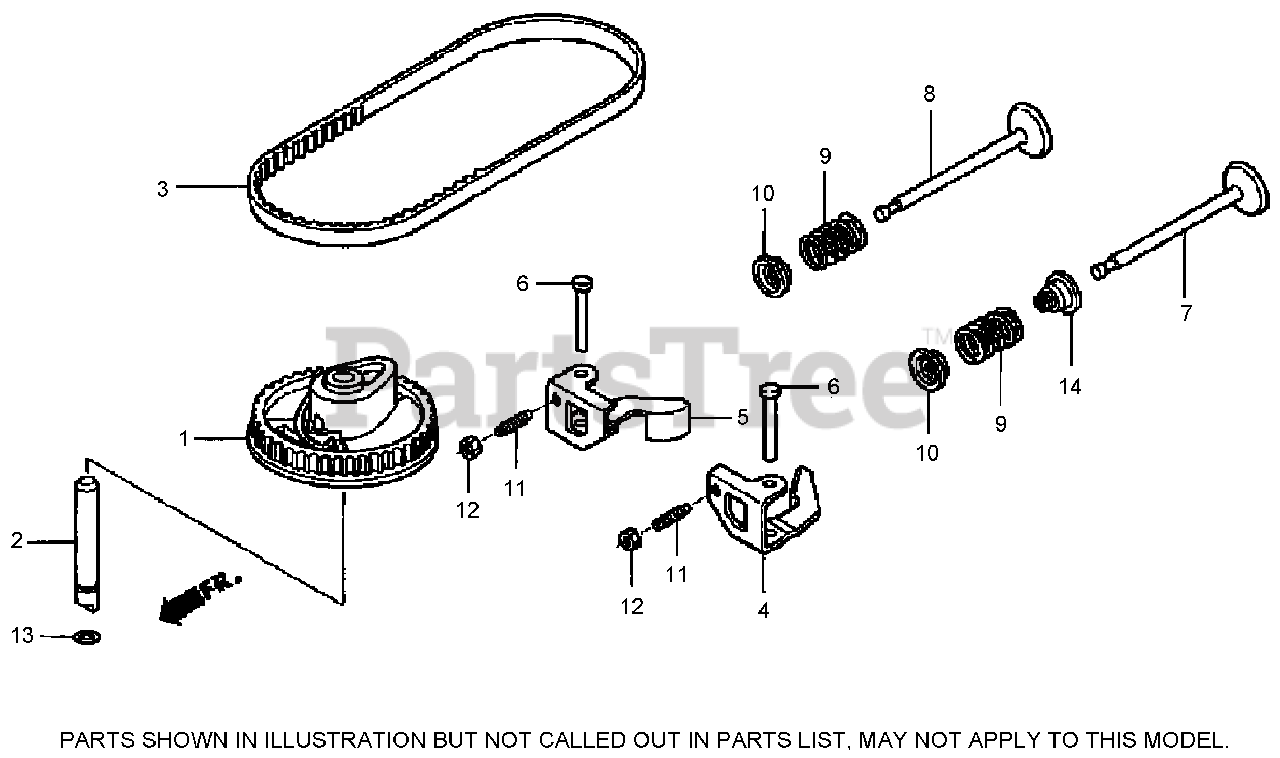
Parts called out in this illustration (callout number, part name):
1	PULLEY, CAMSHAFT
2	SHAFT, CAM PULLEY
3	BELT, TIMING (84HU7 G-
4	ARM, IN. VALVE ROCKER
5	ARM, EX. VALVE ROCKER
6	SHAFT, ROCKER ARM
7	VALVE, IN.
8	VALVE, EX.
9	SPRING, VALVE
10	RETAINER, VALVE SPRING
11	SCREW, TAPPET ADJ.
12	NUT, TAPPET ADJ.
13	O-RING (6.8X1.9)
14	SEAL, VALVE STEM
